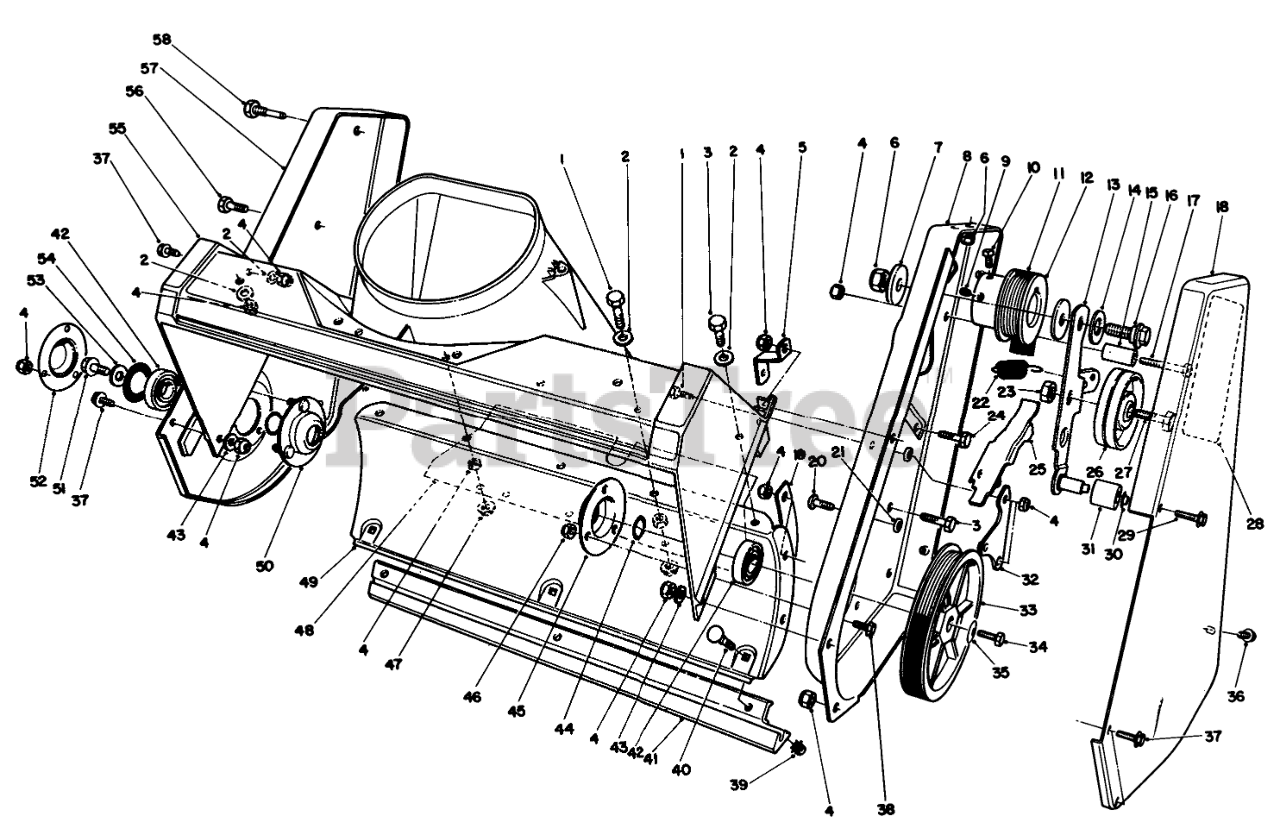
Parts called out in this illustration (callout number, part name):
1	SCREW-HH
2	WASHER-FLAT
3	SCREW-HH
4	NUT-LOCK, NI
5	BRACKET-HOUSING
6	NUT-LOCK, NI
7	WASHER-PIVOT
8	Sideplate-L.H.
9	SCREW-HSH
10	SCREW-SQH
11	BELT - DRIVE
12	ENGINE PULLEY
13	Idler Arm Assembly (Incl. Ref. #29 & 30)
14	WASHER
15	SLEEVE-GUIDE, BELT
16	SCREW-SHOULDER
17	SCREW-HH
18	Cover-Drive
19	BRACKET-HOUSING, LOWER
20	SCREW-HSBH
21	SPACER-PLATE, PIVOT
22	SPRING-EXTENSION
23	NUT-LOCK, CONE
24	SCREW-HH
25	BRAKE-ARM
26	PULLEY-IDLER
27	SCREW-HH
28	DECAL
29	SCREW-HWH, TAP
30	NUT-PUSH
31	ROLLER-BRAKE
32	PIVOT PLATE ASM
33	ROTOR PULLEY ASY
34	SCREW-HH
35	WASHER-BELLEVILLE
36	SCREW
37	SCREW-HWH
38	SCREW-SHH
39	NUT-KEPS
40	SCREW-CARR
41	SCRAPER
42	BEARING-BALL
43	WASHER-FLAT
44	WASHER-THRUST
45	FLANGE-BEARING
46	NUT-LOCK, NI
47	NUT-LOCK, HHF
48	COVER-BOTTOM
49	Housing-Lower
50	FLANGE-BEARING
51	SCREW-HHF
52	Trough
53	WASHER-FLAT
54	WASHER-RUBBER
55	HOUSING
56	SCREW-HH
57	Sideplate-RH
58	PIN-ROTOR
